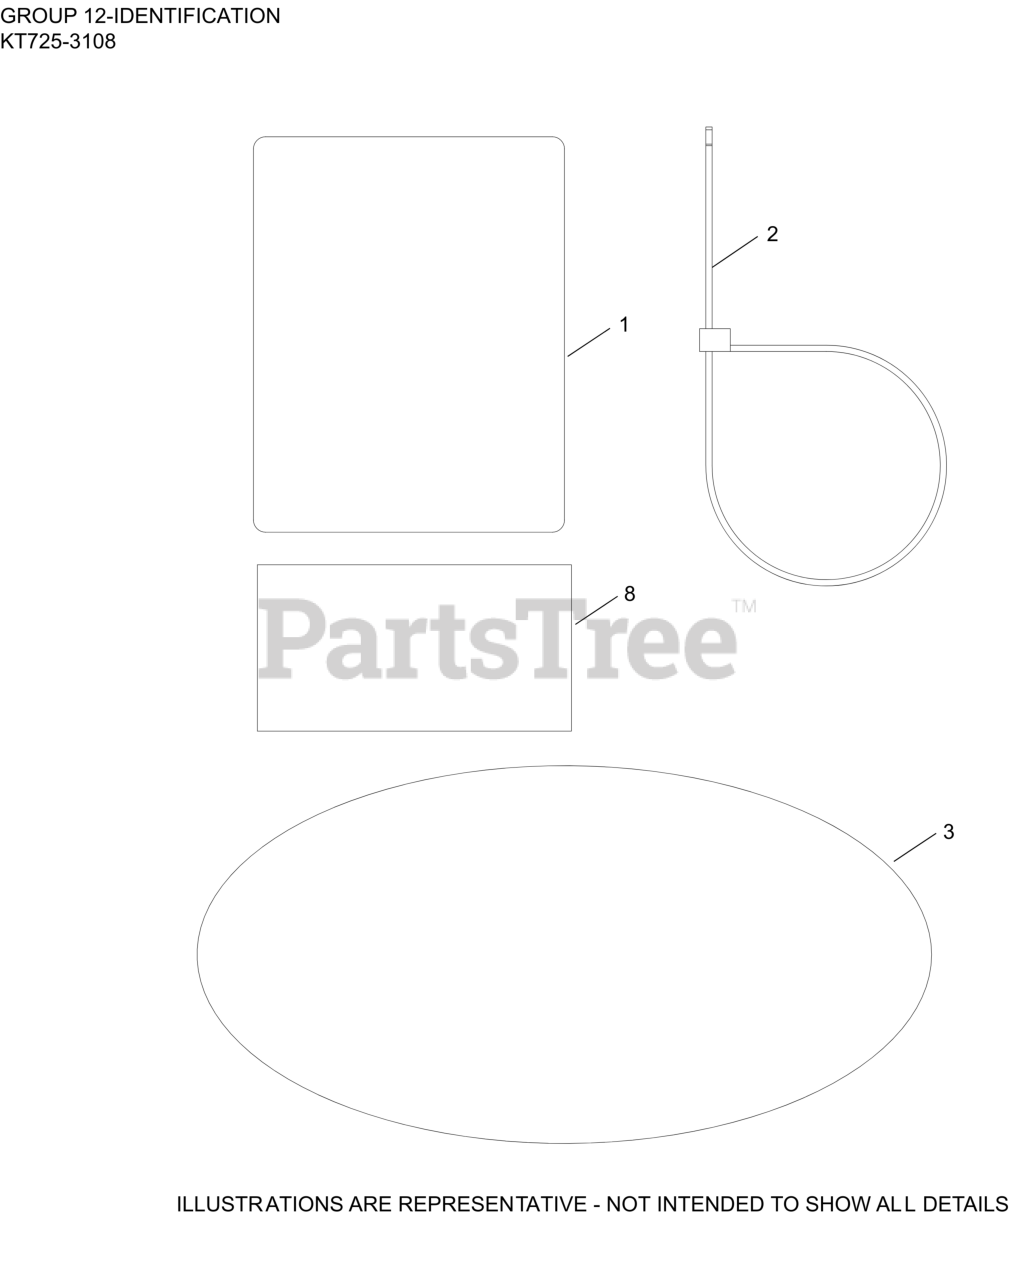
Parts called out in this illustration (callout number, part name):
1	LABEL, CLEAR LAMINATION
3	LABEL, 7000 SERIES KT725 (22 HP)
8	DECAL, USA
